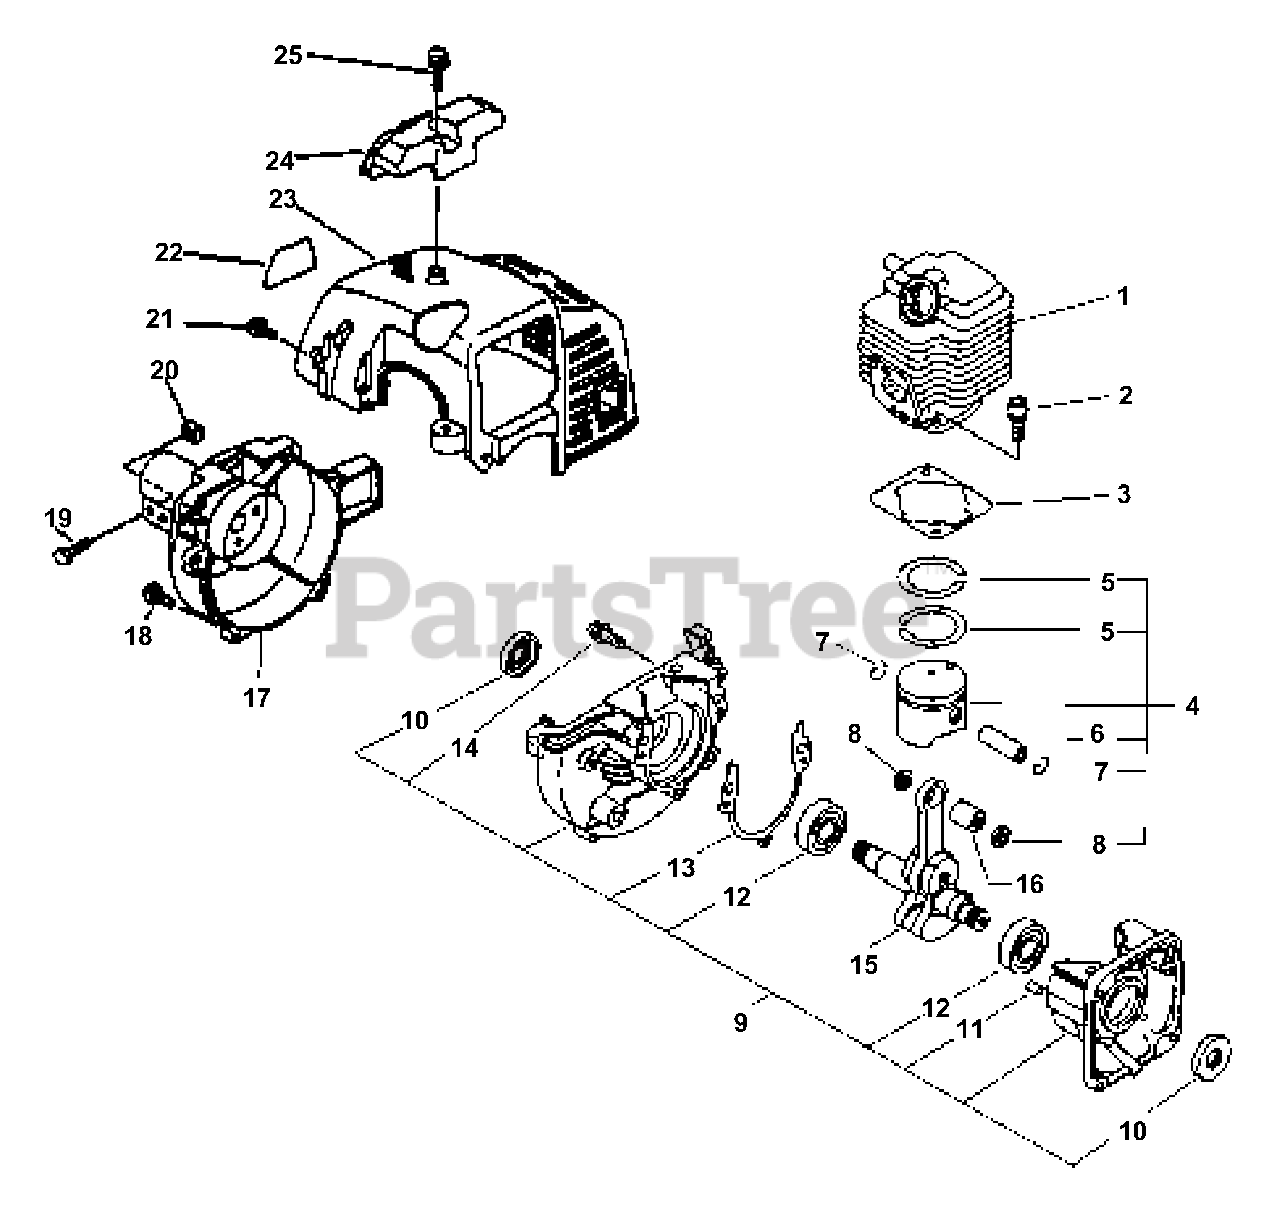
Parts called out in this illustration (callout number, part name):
1	CYLINDER
2	BOLT 5×22
3	GASKET, CYLINDER
4	PISTON KIT
5	RING, PISTON
6	PIN, PISTON 8
7	RING, SNAP
8	WASHER, THRUST
9	CRANKCASE KIT
10	SEAL, OIL 12
11	PIN, LOCATING 4
12	BEARING, BALL - 6201 C3
13	GASKET, CRANKCASE
14	BOLT 5×28
15	CRANKSHAFT ASSY
16	BEARING, NEEDLE
17	COVER ASSY, FAN
18	BOLT 5×14
19	BOLT 5×28
20	NUT M5
21	SCREW 4×12
22	LABEL, PE-2000
23	COVER, ENGINE - GRAY
24	GUARD, TOP - GRAY
25	SCREW 5×16
